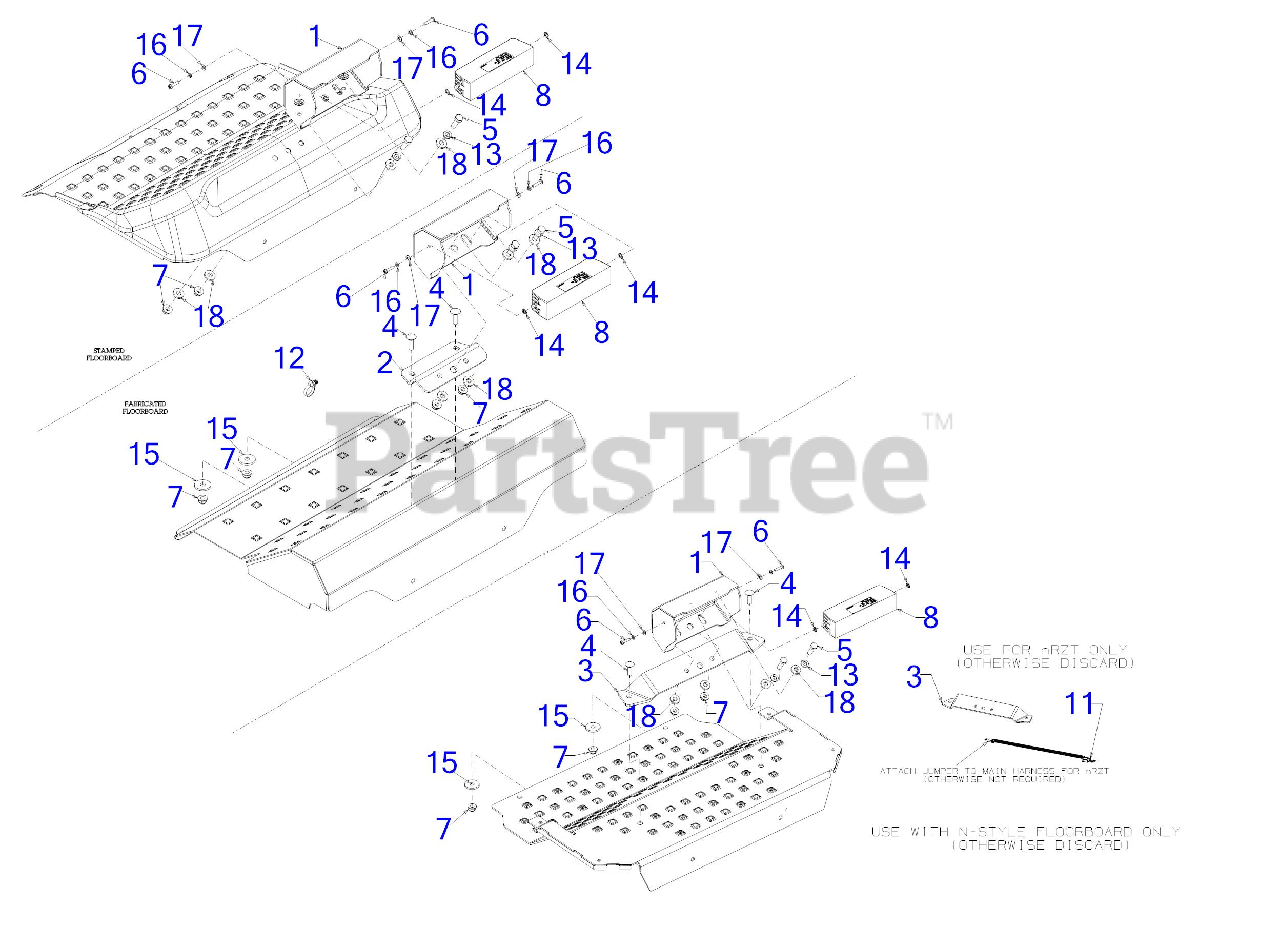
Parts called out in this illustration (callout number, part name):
4	CARRIAGE BOLT 5/16-18 x 1.00
5	SCREW 5/16-18 x 1.0 GR5
6	SCREW #8-32 x .750
7	FLANGE LOCK NUT 5/16-18
8	HEADLIGHT ASSEMBLY
11	HEADLIGHT JUMPER HARNESS 2.0"
12	CABLE TIE
13	LOCK WASHER 5/16
14	LOCK WASHER
15	FLAT WASHER
16	LOCK WASHER
17	FLAT WASHER .203 ID x .41 OD x .040
18	FLAT WASHER
